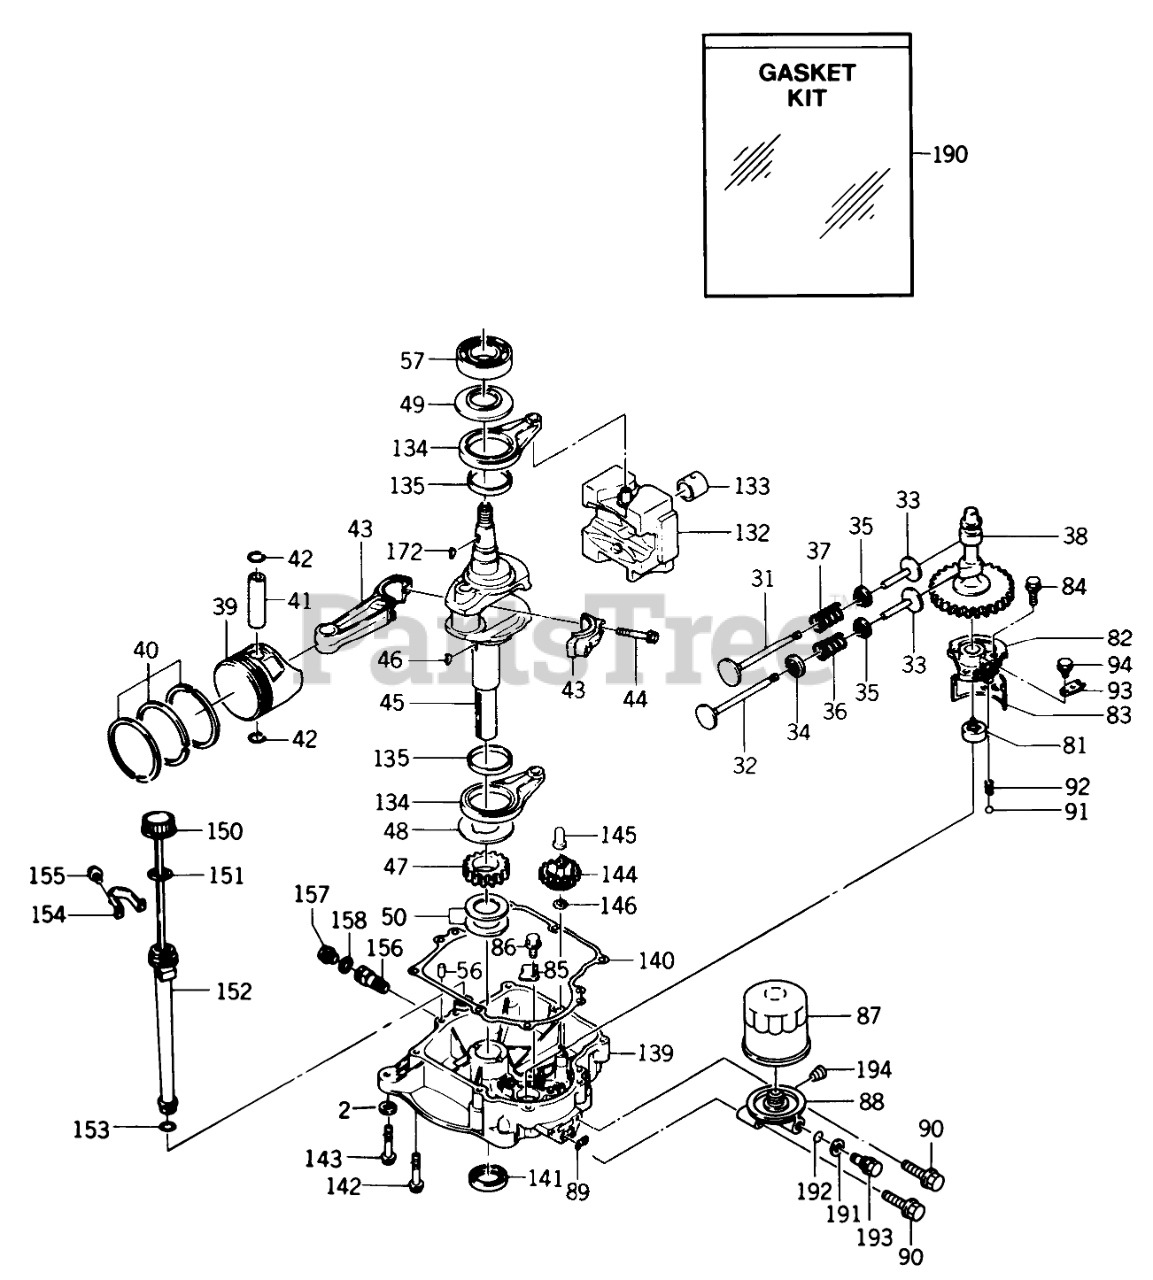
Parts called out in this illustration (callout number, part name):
2	920008 Washer 5/16 SAE
31	VALVE-INTAKE
32	VALVE-EXHAUST
33	TAPPET-VALVE
34	ROTATOR-VALVE
35	RETAINER-VALVE
36	SPRING-VALVE
37	SPRING-VALVE
38	SHAFT-CAM
39	PISTON-(STD)
39	PISTON-.010 OVER
39	PISTON-.020 OVER
39	PISTON-.030 OVER
40	RING (STD)
40	RING (.010 OVER)
40	RING (.020 OVER)
40	RING (.030 OVER)
41	PIN-PISTON
42	RING-SNAP
43	13251-6005 Connecting Rod Ass-y-Standard (includes item 44)
43	13251-6007 Connecting Rod Assty-.025mm Under Size (Includes item 44)
44	BOLT-CON ROD
45	CRANKSHAFT
46	KEY-WOODRUFF
47	GEAR-HELICAL
48	SPACER
49	SPACER
50	SHIM-T=1.18
50	SHIM-T=1.25
50	SHIM-T=1.32
50	SHIM-T=1.39
50	SHIM-T=1.46
50	SHIM-T=1.53
50	SHIM-T=1.60
50	SHIM-T=1.67
50	SHIM-T=1.74
57	BEARING-BALL #6207
81	PUMP OIL
82	COVER-PUMP
83	FILTER-INTERNAL OIL
84	BOLT, FLANGED 8X25
85	PLATE
86	Bolt
87	Filter-Oil
88	11044-2065 Bracket (includes item 194)
89	RING O
90	BOLT-FLANGED
91	BALL-STEEL 5/16
92	SPRING
93	PLATE
94	BOLT-FLANGED
132	13042-6006 Weight Complete (includes item 133)
133	BEARING-PLAIN
134	46102-6001 Rod Assy (includes item 135)
135	BEARING PLAIN
139	COVER-CRANKCASE
140	GASKET
141	SEAL OIL
142	BOLT-FLANGED
143	BOLT, FLANGED 8X25
144	GOVERNON
145	SLEEVE-GOVERNOR
146	WASHER
150	GAUGE-OIL
151	GASKET
152	FILLER
153	O-RING
154	CLAMP
155	Bolt
156	JOINT
157	PLUG DRAIN
158	GASKET
172	KEY-WOODRUFF
190	GASKET SET-OVERHAUL
191	11009-2175 Gasket
192	O'RING
